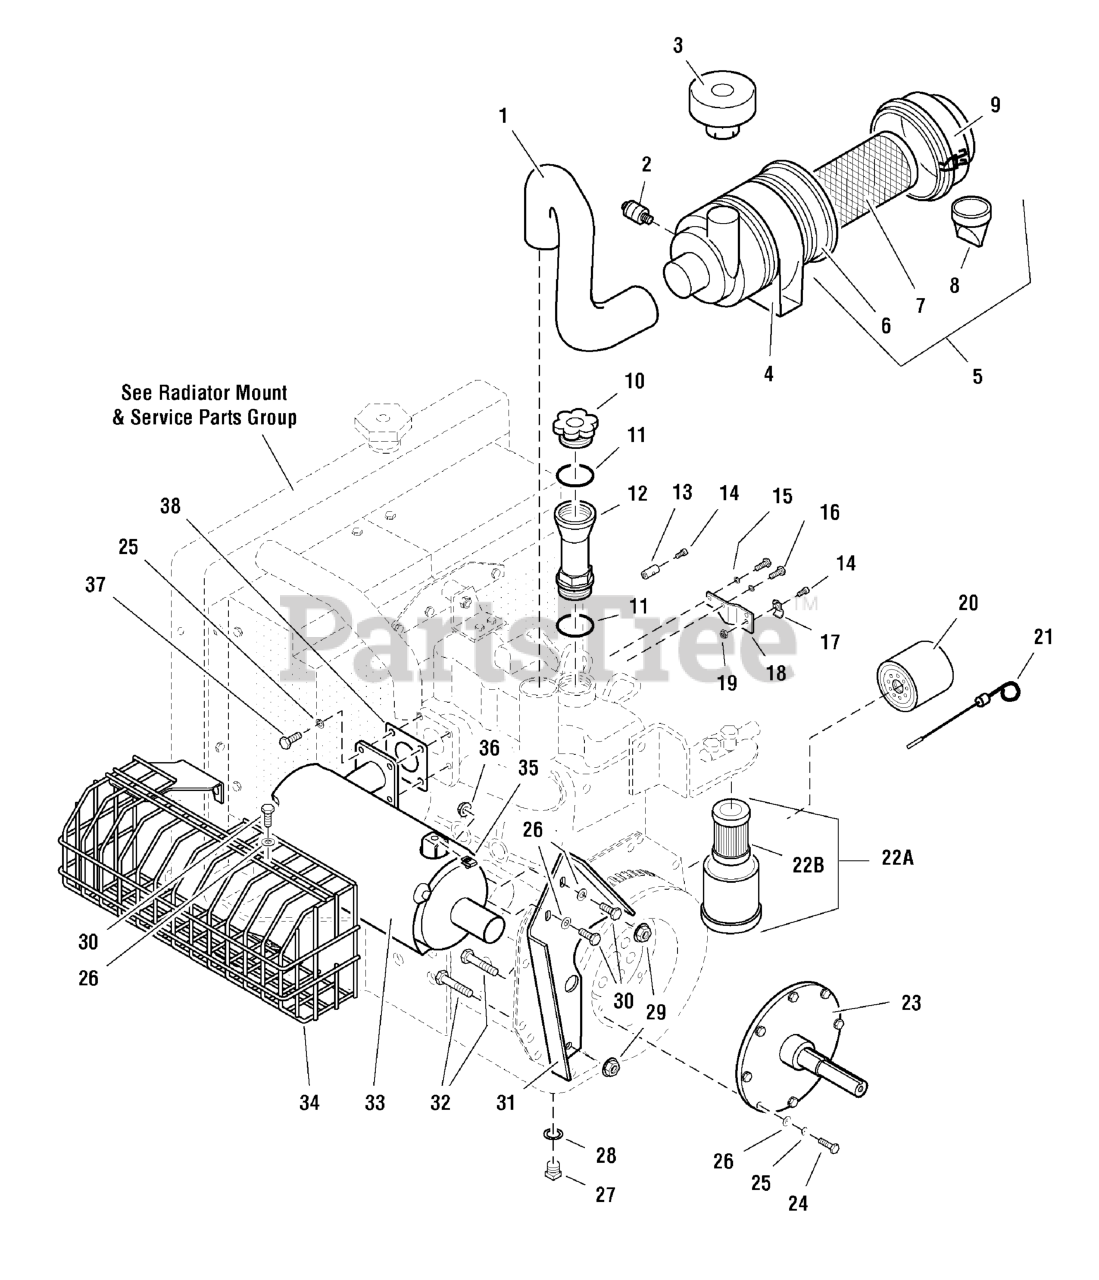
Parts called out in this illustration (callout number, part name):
1	AIR INLET HOSE
1	HOSE CLAMP
2	AIR CLEANER INDICATOR
3	PRE-CLEANER
4	AIR CLEANER BRACKET
5	AIR CLEANER ASSEMBLY, Complete
6	AIR CLEANER HOUSING ASSEMBLY
7	AIR CLEANER ELEMENT
8	AIR CLEANER DUST VALVE
9	AIR CLEANER COVER
10	OIL FILL CAP
11	OIL FILL O-RING SEAL
12	OIL FILL EXTENSION
13	BARREL CLAMP
14	SCREW, #10-24 x 3/4
15	WASHER, 1/4 LOCK
16	BOLT, M6 x 10MM
17	CLAMP
18	THROTTLE BRACKET
19	NUT, #10-24 Hex Nylon Lock
20	OIL FILTER
22A	FUEL FILTER ASSEMBLY, Complete
22B	FILTER ELEMENT
24	BOLT, 5/16-18 x 1-1/4
25	WASHER, 5/16 LOCK CZ
26	WASHER, 5/16" SAE
27	OIL PAN PLUG
28	WASHER, Oil Pan Plug
29	NUT, 3/8-16 Hex Serrated Flange
30	BOLT, 5/16-18 X 1 GD5 YZ
31	MUFFLER SUPPORT
32	BOLT, 3/8-16 X 1-3/4" GD5 CZ
33	MUFFLER
34	WELD, MUFFLER GUARD - BLK
35	BODY CLIP, 5/16-18-7GA MATERIAL
36	NUT, 5/16-18 HEX SERRATED FLANGE (SMALL)
37	BOLT, M8-1.25 X 25MM GR 8.8
38	GASKET, EXHAUST MANIFOLD - NET
39	FUEL SOLENOID
40	WASHER, Fuel Solenoid
41	WATER PUMP
42	WATER HOSE-UPPER
43	WATER HOSE-LOWER
44	GASKET, Water Pump
45	THERMOSTAT
46	GASKET, Thermostat
47	STARTER MOTOR
48	ALTERNATOR
49	BELT
50	FUEL PUMP,# 295-4070 - NET
51	GASKET, Fuel Pump
52	GLOW PLUG
53	RADIATOR
54	SWITCH, Oil Pressure
55	SWITCH, Water Temperature
56	STARTER SOLENOID
57	SEAL, REAR MAIN - NET
58	SEAL, Front Main
59	INJECTOR ASSEMBLY
60	WASHER, 4-HOLE
61	WASHER, SEALING
62	WASHER, CRUSH
